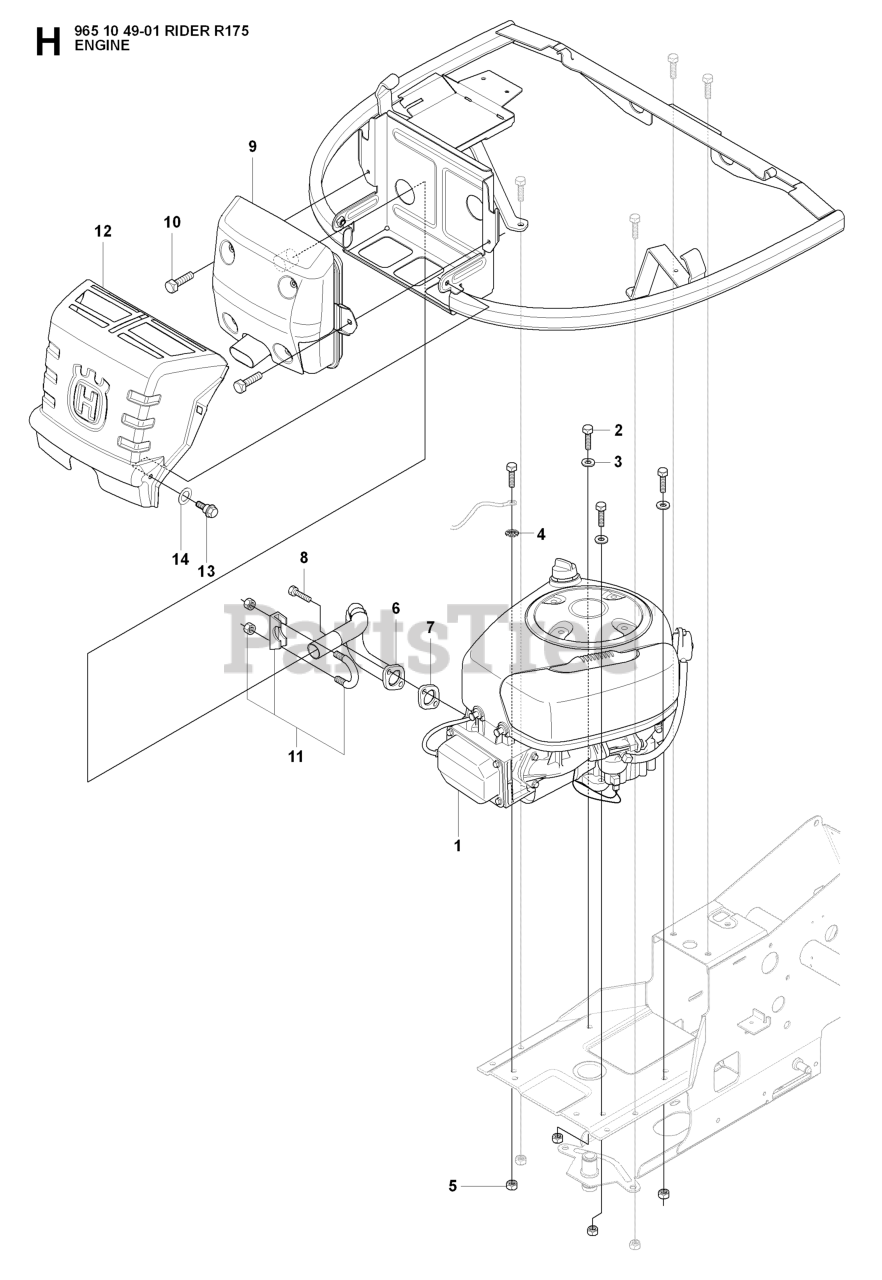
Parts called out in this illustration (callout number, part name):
3	WASHER BRB 8.4X17
5	LOCKNUT M8
6	EXHAUST PIPE ASSY
9	MUFFLER ASSY
11	CLAMP
12	HEAT PROTECTOR
14	SPRINGWASHER
